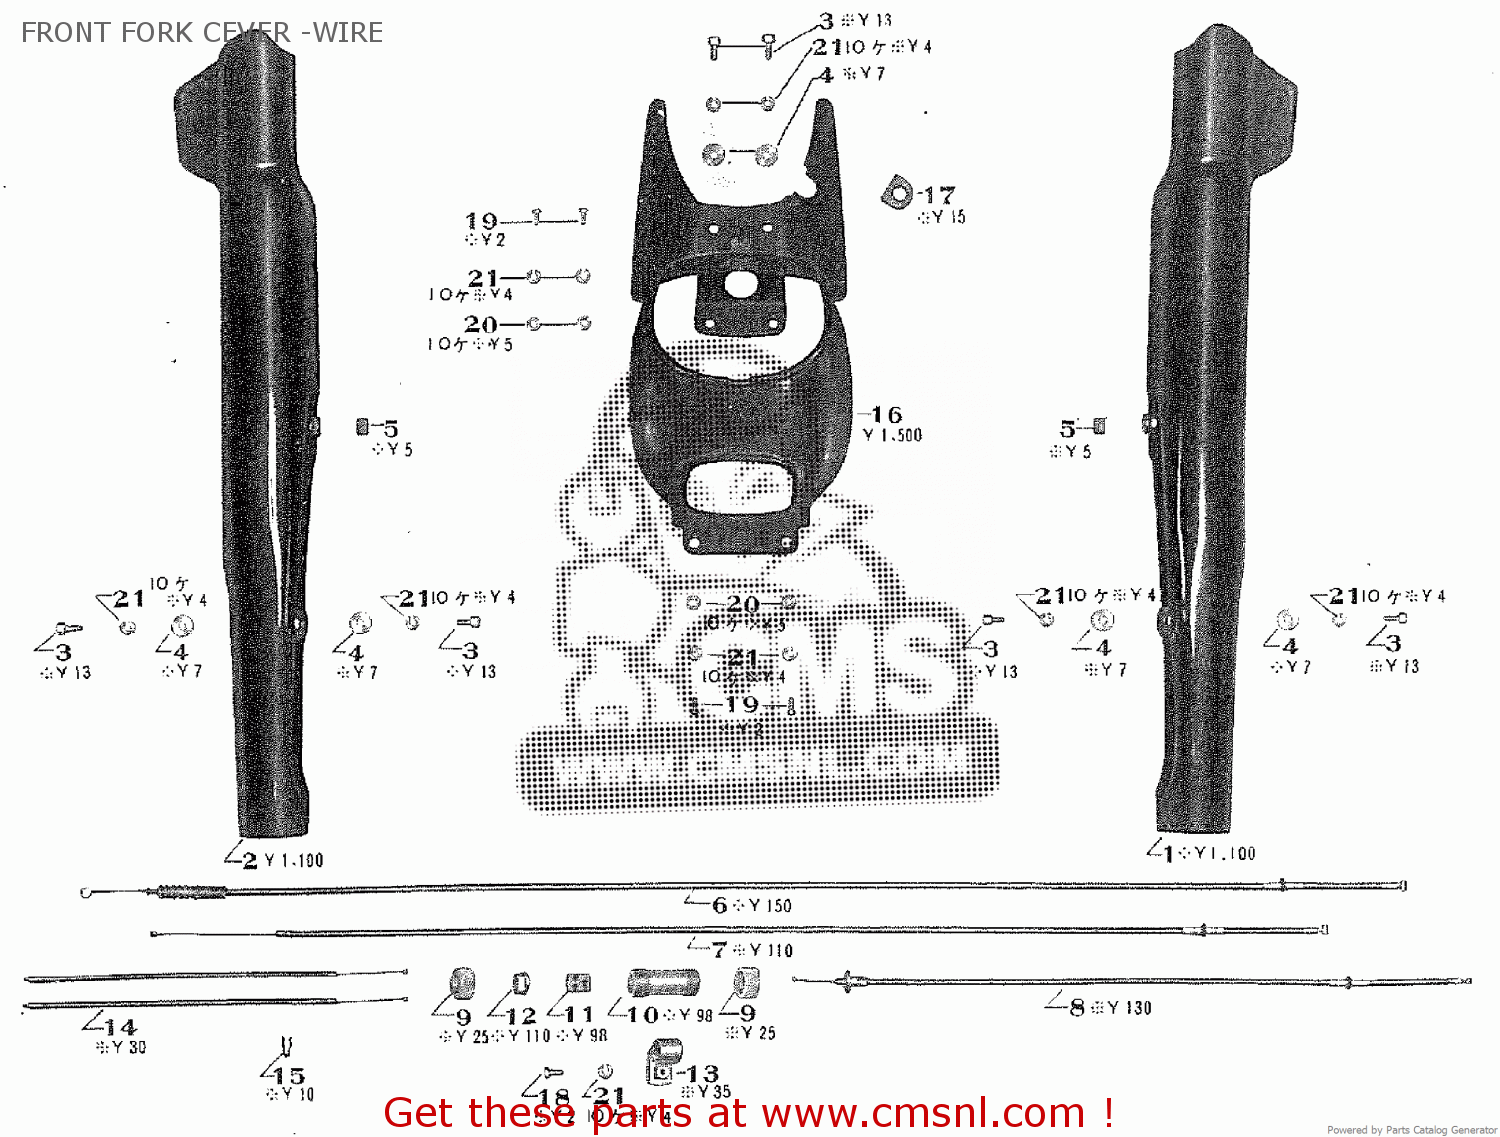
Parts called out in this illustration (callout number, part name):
1	RIGHT FRONT FORK COVER COMP.
2	LEFT FRONT FORK COVER COMP.
3	BOLT
4	WASHER
5	HEAD LAMP HOLDER SET RUBBER
6	BRAKE WIRE COMP.
7	CLUTCH WIRE COMP
8	THROTTLE WIRE ASSY.
9	CONNECTOR NUT
10	CONNECTOR PIPE
11	CONNECTOR SLIDING PIECE
12	CONNECTOR CAP
13	CONNECTOR SET BAND COMP.
14	15
15	THROTTLE WIRE CLIP
16	HEAD LAMP HOLDER COMP.
17	HEAD LAMP HOLDER SET BUSH
18	6X12 HEXAGON BOLT
19	6X12 CROSS SCREW
20	6MM PLANE WASHER
21	6MM SPRING WASHER
